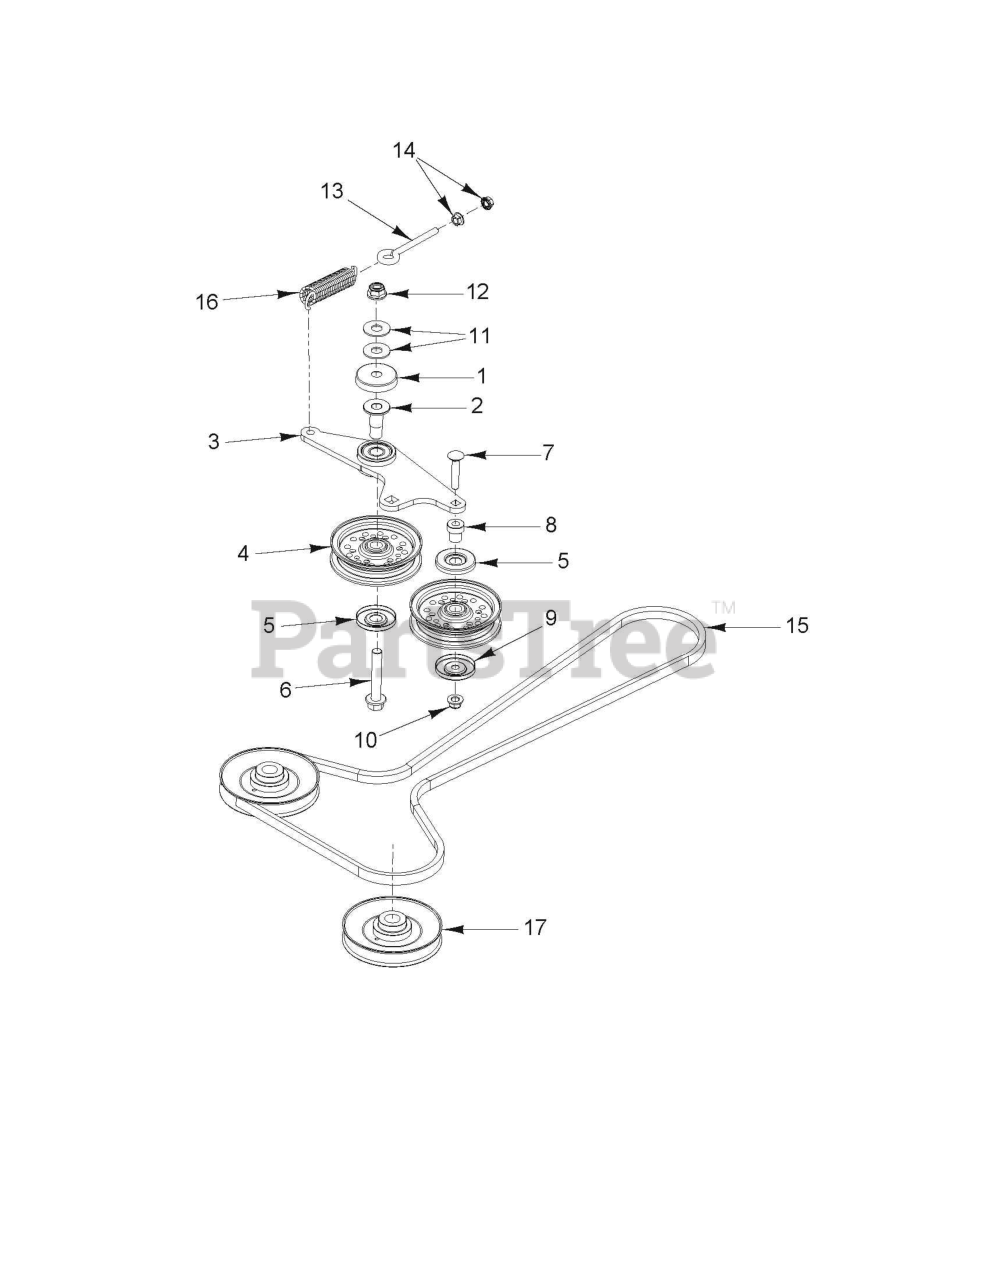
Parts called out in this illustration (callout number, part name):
1	SHIELD, DUST
2	BUSHING, PIVOT
3	ARM, IDLER W/BEARING
4	IDLER PULLEY
5	SHIELD, DUST
6	Bolts
7	Bolts
8	PIVOT, IDLER
10	GSPW Nuts
11	Washers
12	NUT 1/2-13 HEX FLANGE NYLOK CL
13	GSPW Bolts
14	GSPW Hardware
15	V-BELT GROUND DRIVE 79.52" STA
16	SPRING, PUMP
17	PULLEY PUMP, 5 INCH
